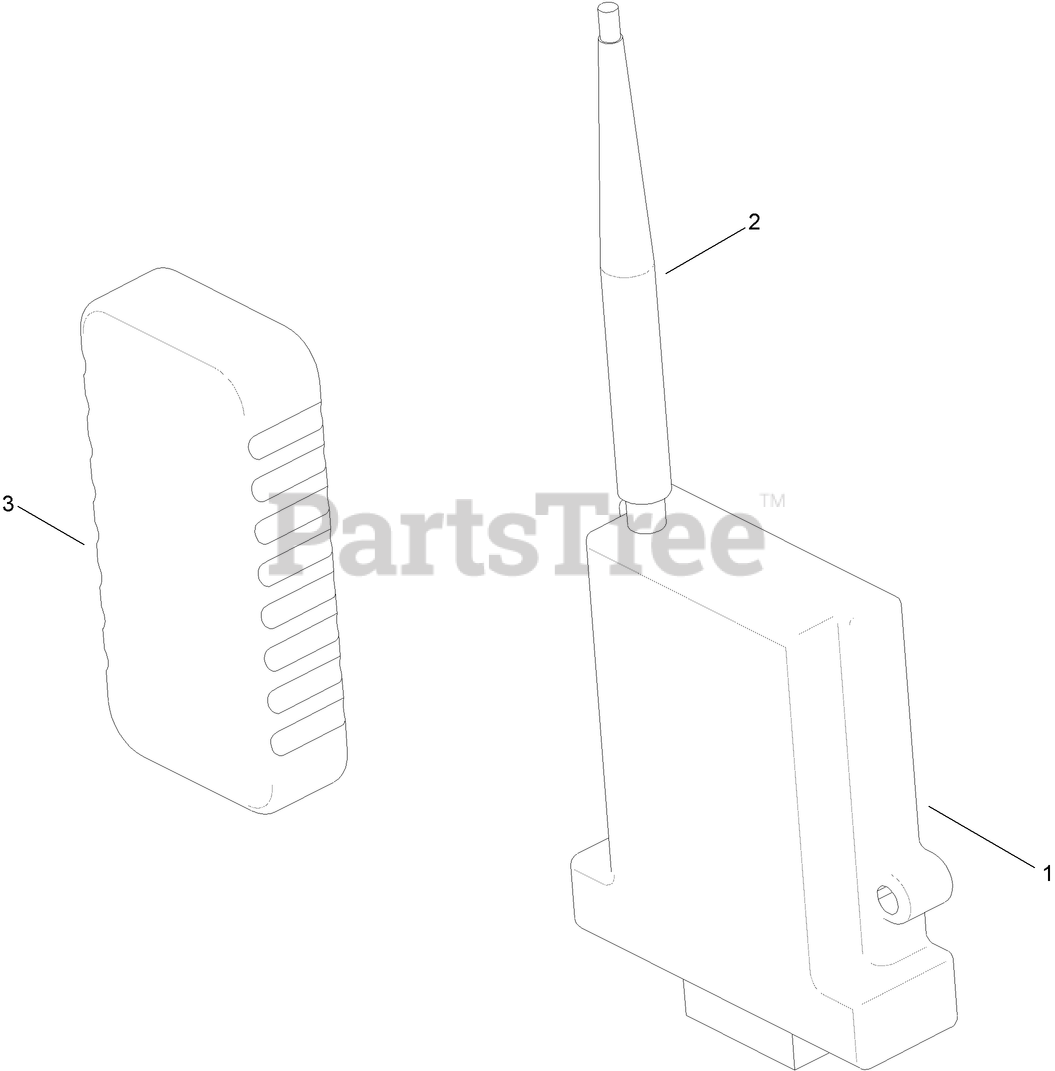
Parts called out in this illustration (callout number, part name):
1	BASE UNIT-LOCKOUT
2	ANTENNA-LOCKOUT
3	HANDHELD-LOCKOUT
